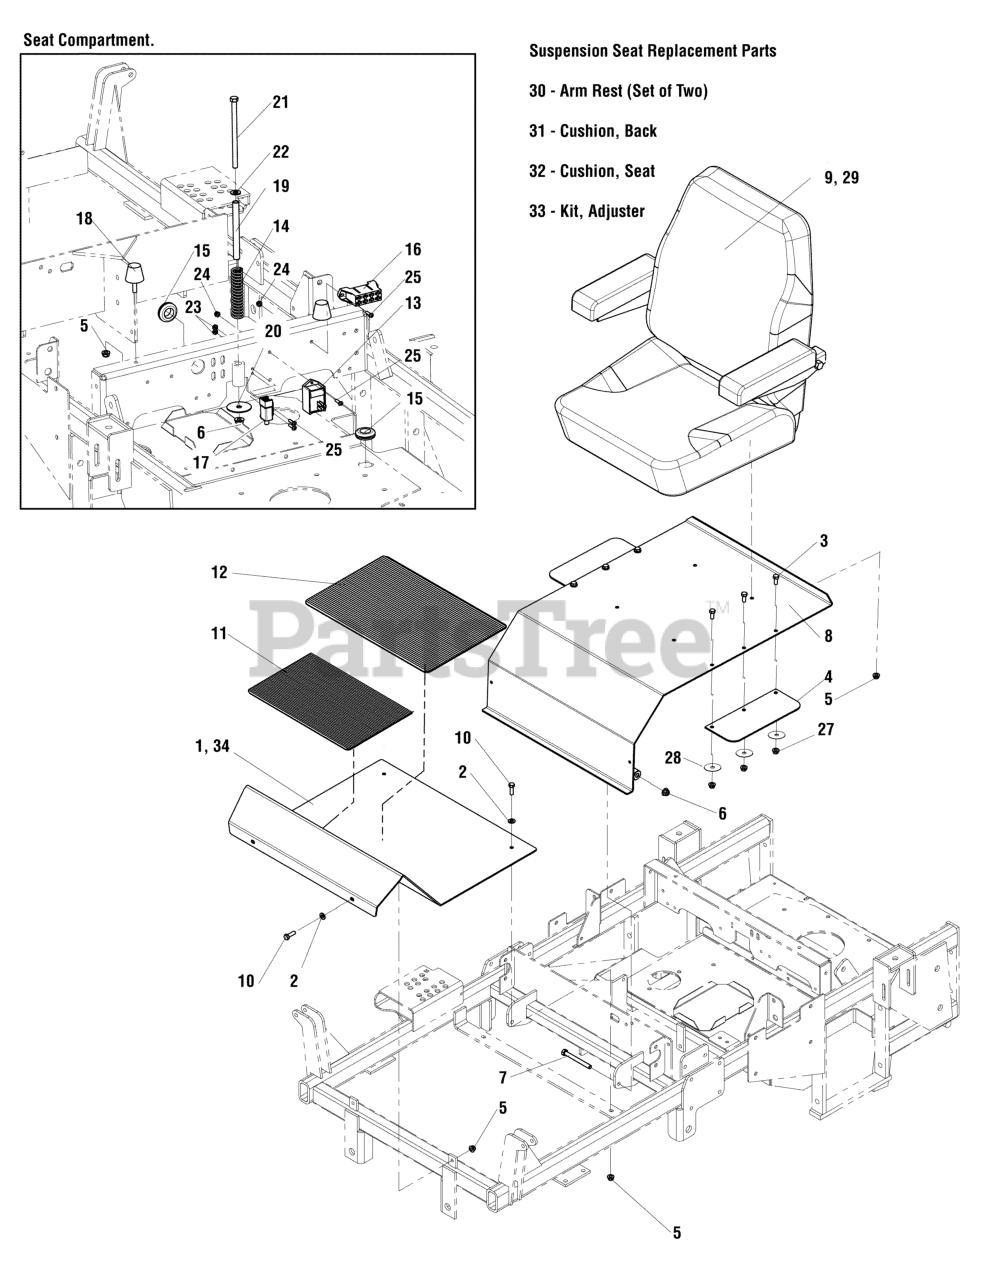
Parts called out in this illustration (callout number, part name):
1	FLOOR PAN, 3000 - RED
2	WASHER, 5/16" SAE
3	BOLT,1/4-20X0.750,GR5,STD NECK,SQ,ZC/CL
4	PLATE, SEAT, RUBBER FLAP
5	NUT, 5/16-18 HEX NYLOCK FLANGE
6	NUT, 3/8-16 HEX NYLOCK FLANGE
7	BOLT, 3/8-16 X 3-1/2" GD5 CZ
8	SEAT PLATE W/ DECALS, IS3100Z
10	BOLT, 5/16-18 X 1" GD5
11	SAFETY WALK, FLOOR REST
12	SAFETY WALK, FLOOR PLATE
13	MODULE, TIME DELAY
14	SPRING, .688 ID X .130 WIRE DIA 4.25
15	GROMMET, 7/8"
16	FUSE, BLOCK
17	SWITCH PLUNGER N.C. / N.C.
18	BUMPER, RUBBER 5/16-18
19	SPACER, .38 X .50 X 5.06
20	WASHER 3/8" X 2
21	BOLT, 3/8-16 X 6" GD5 CZ
22	WASHER, 3/8 SAE
23	NUT, 10-24 HEX
24	NUT, #10-24 HEX NYLON LOCK
25	SCREW, #10-24 X 1/2" ROUND SLOTTED
27	NUT, 1/4-20 HEX NYLOCK FLANGE
28	WASHER, 1/4" FENDER
29	SEAT, SUSPENSION TYPE, BLACK
30	KIT, ARM REST, S/S (SV)
31	CUSHION, BACK, S/S (SV)
32	CUSHION, SEAT, S/S (SV)
33	KIT, ADJUSTER, S/S (SV)
34	PLATE, FLOOR PAN, IS3100 - RED
